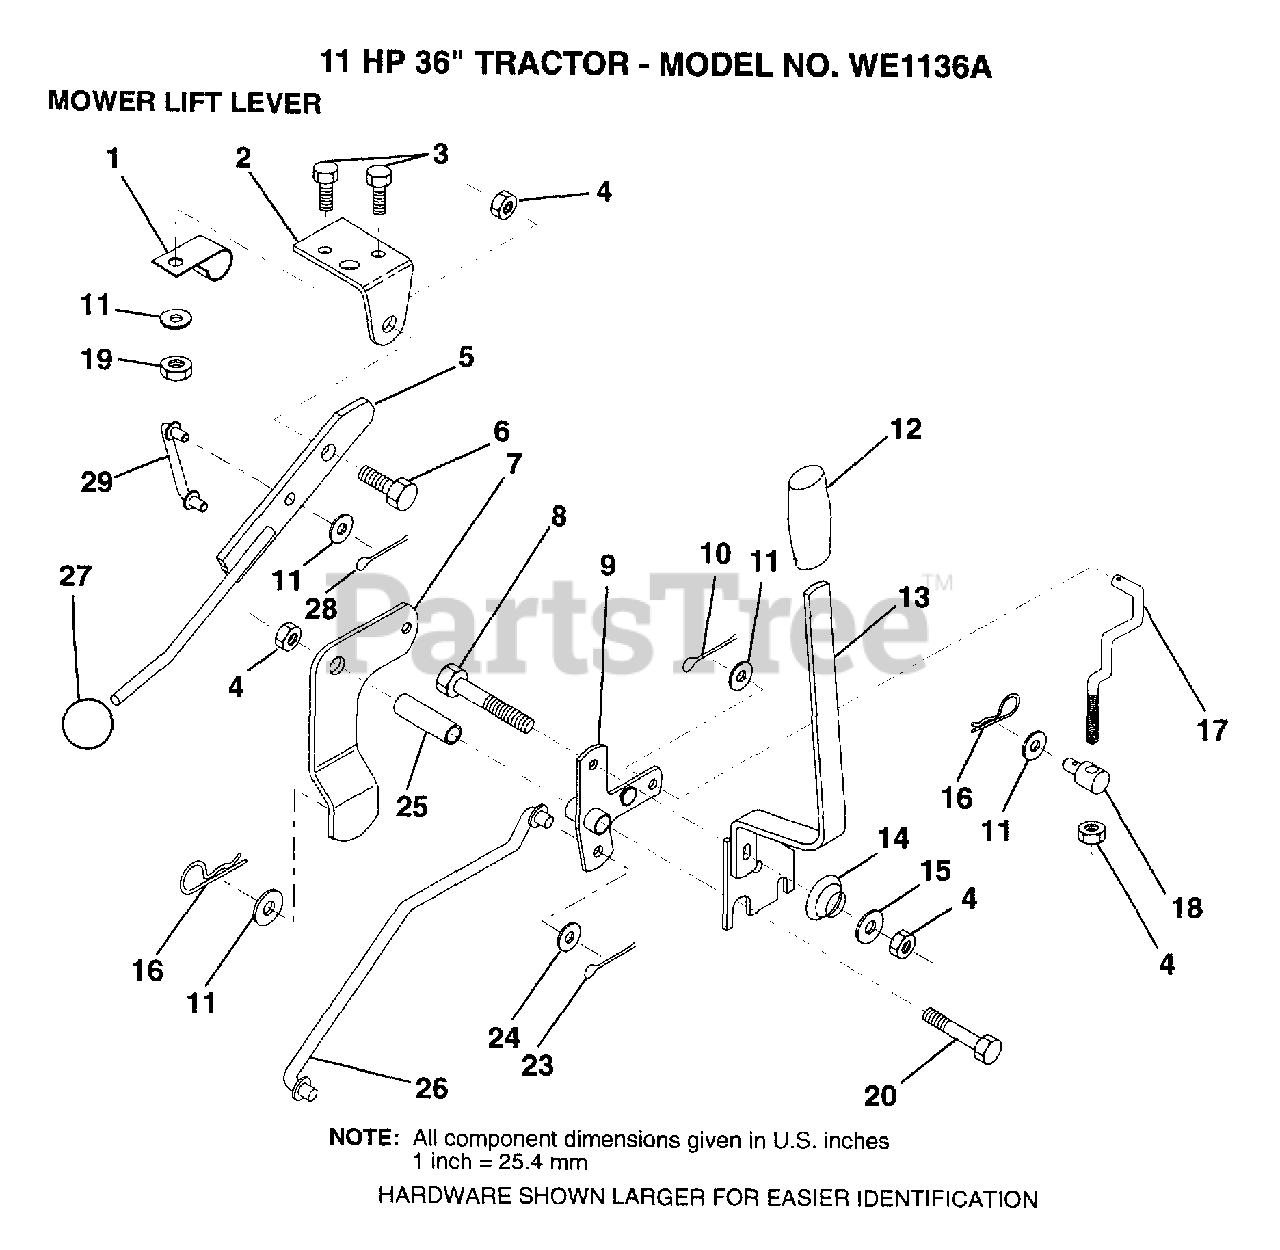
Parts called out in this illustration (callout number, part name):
1	"CLIP,INSULATOR"
2	BRKT CLUTCH
3	BOLT
5	CLUTCH LEVER AS
6	"BOLT, SHOULDER LT"
7	MWR CLUTCH ARM AS
8	BOLT
9	"BELLCRANK,LIFT"
10	COTTER PIN
11	WASHER
13	"HDLE,LIFT T"
14	SPRING COMPRESSIO
15	WASHER T
16	SPRING.RETAINER
17	"LINK,LIFT FRT"
18	TRUNION
20	BOLT
23	PIN COTTER 1/8
25	TUBE SPACER
26	"ROD,MOWER LIFT "
27	KNOB T(3/8 HOLE)
29	CLUTCH LINK
